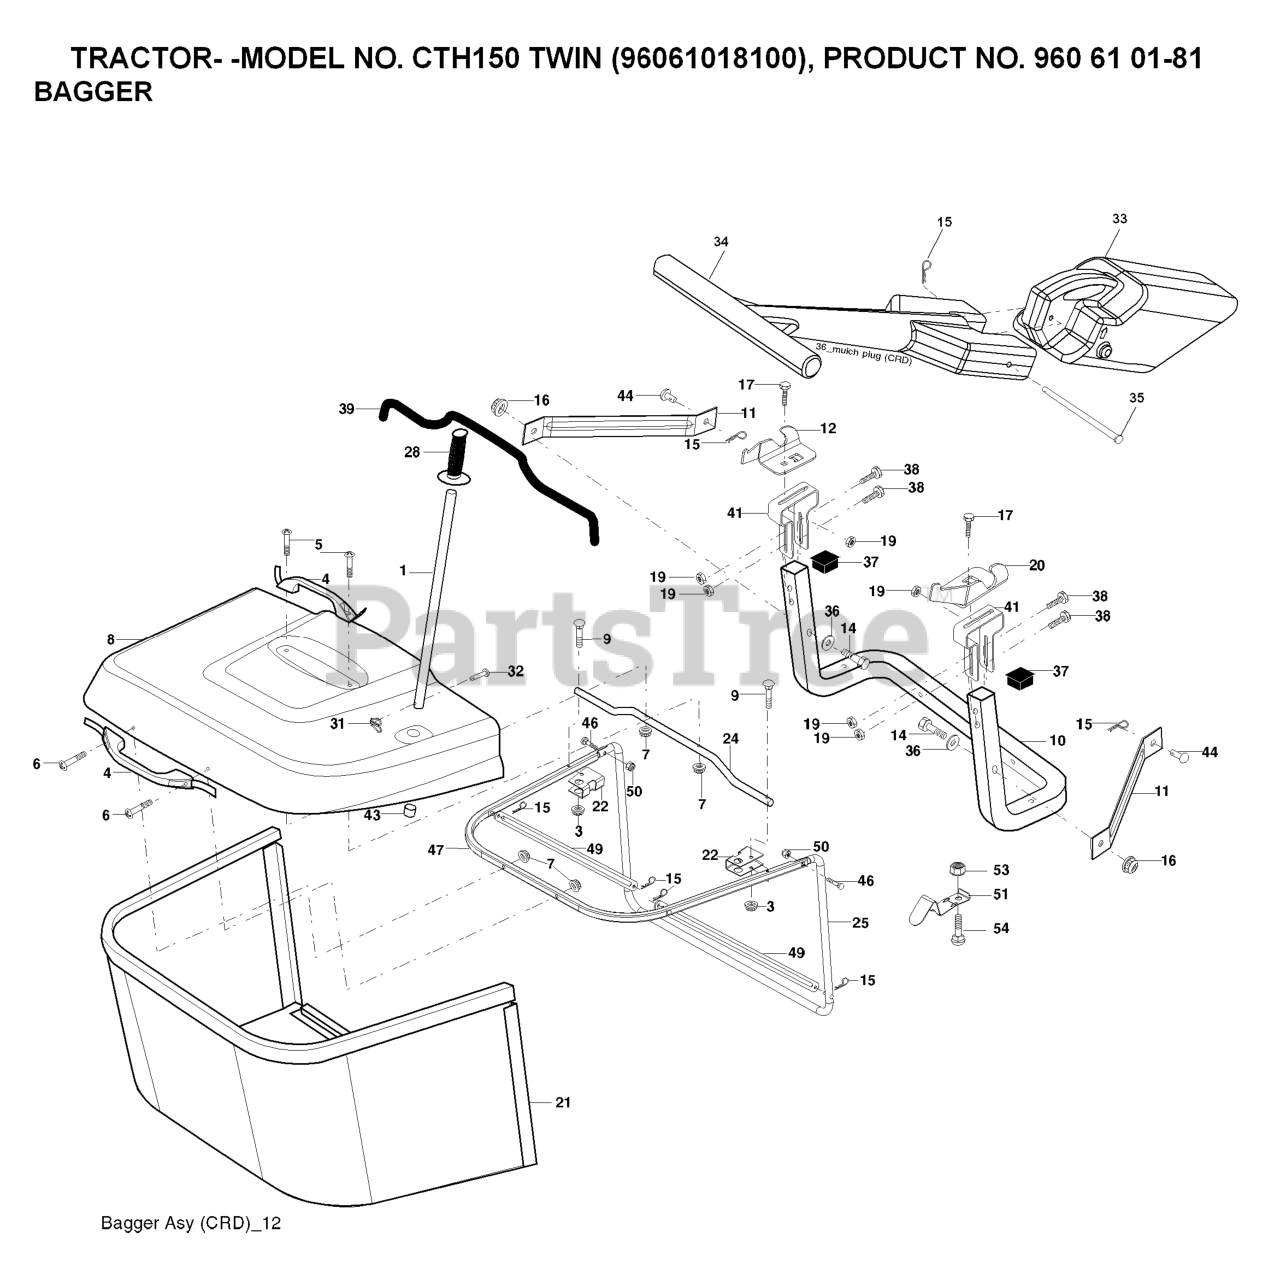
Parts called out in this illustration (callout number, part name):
1	TUBE HANDLE
3	NUT T
4	HANDLE.BAGGER.W/LVRS.BLK.CRD
5	SCREW.PAN.HEAD
6	REPL BY 532 75 00-29
8	COVER.PNT.BGR.CRD.WSLOTS.MS668
9	Bolt Carriage 1/4-20 x 2.25d x Gr.5
10	TUBE
11	BRACKET.SUPPORT.UPPER.BAG.CRD
12	BRKT PIVOT
14	BOLT-HEX EAK
15	RETAINER-SPRNG RB
16	NUT LOCK FLG 3/8-16 UNC
17	RP BOLT 5/16-18 X3/4 ZN/YEL GR
19	NUT LOCK HEX FLANGE 5/16-18
20	BRKT.PIVOT.RH.CRD
21	BAGGER.ASM.CRD.2007
22	BRKT.SIDE.BAG.CRD
24	TUBE.PIVOT.BAG.CRD.BLACK
25	PIPE
28	GRIP.HANDLE.BLACK
31	RETAINER CLIP
32	RIVET,DRILLED
33	MULCH PLUG, CTH150
34	HANDLE.MULCHER.92.CRD (2 2)
36	WASHER
37	Plug Support Bagger CRD
38	BOLT.5/16-18X2.5
39	SEAL.TRIM.37'
41	BRKT.VERT.ADJ.BAGGER.CRD
43	PLUG, TUBING END
46	BOLT.CARRIAGE.5/16-18
47	PIPE
49	ROD
50	NUT.71038.31-18.HEX.NYLOCK
51	LATCH
53	NUT
54	BOLT
